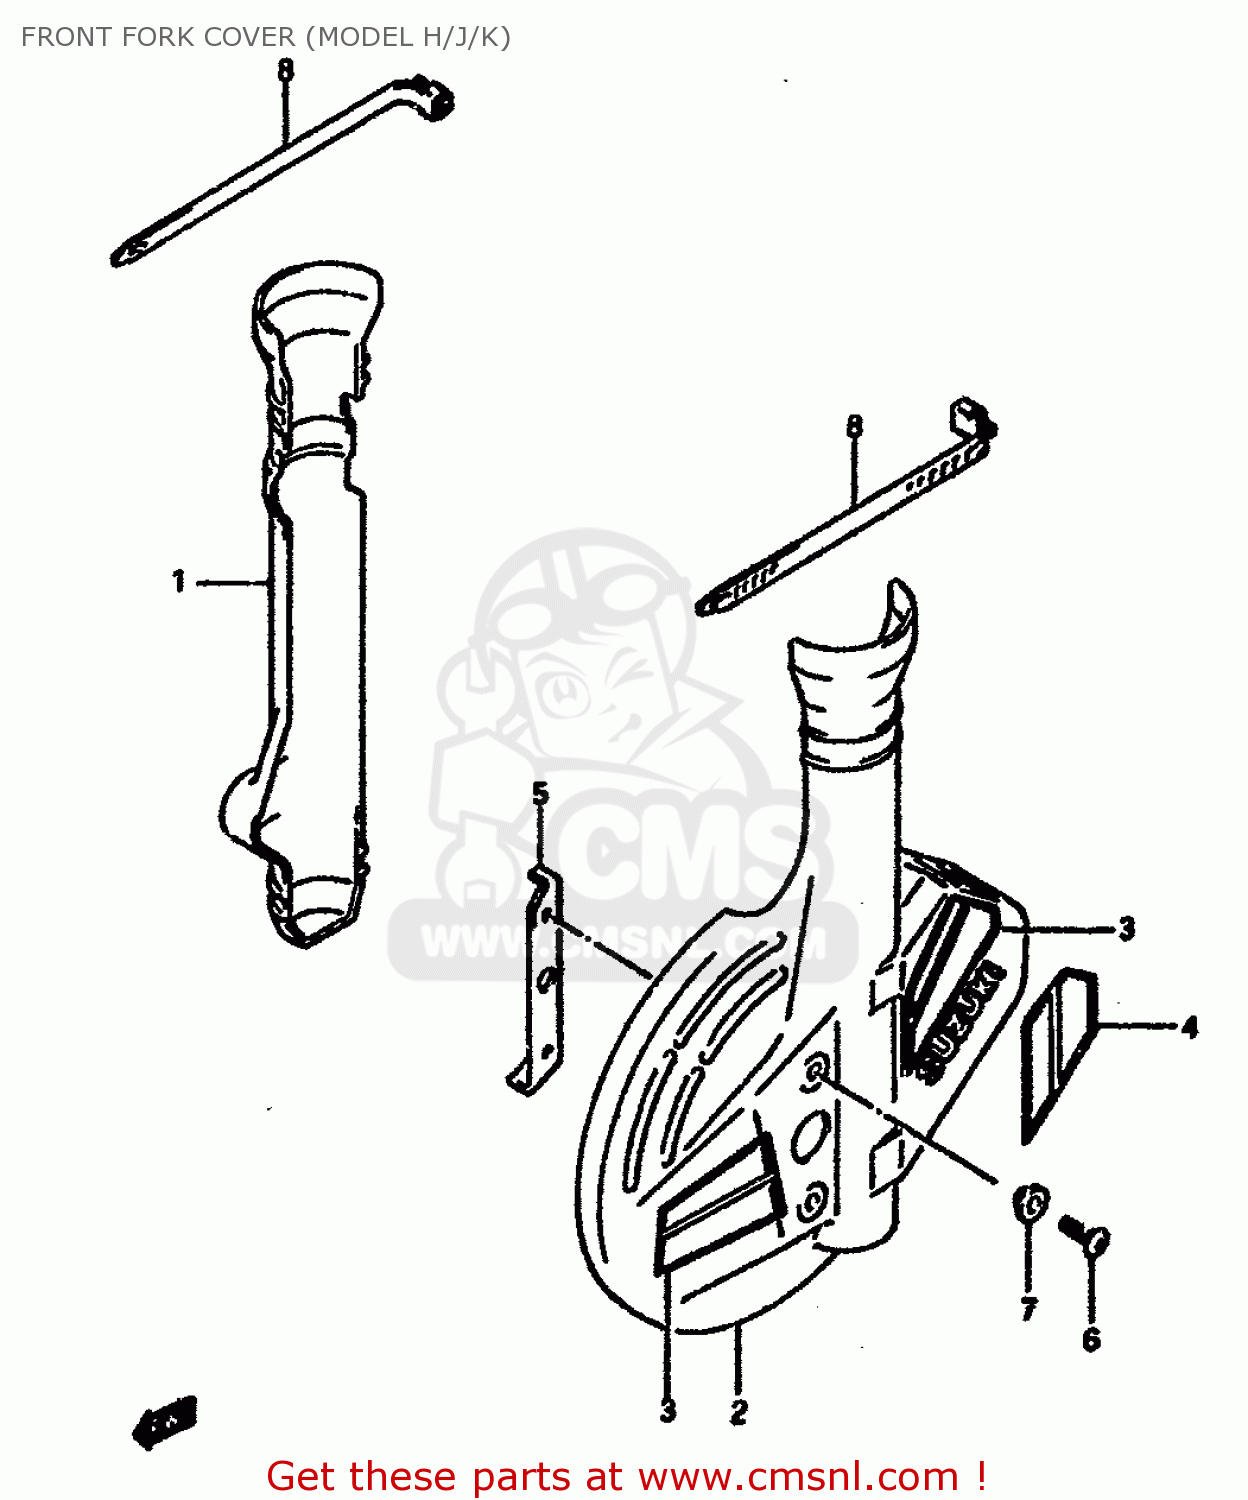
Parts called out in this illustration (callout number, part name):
1	PROTECTOR, FRONT FORK RH
2	PROTECTOR, FRONT FORK LH
3	TAPE SET,DISC PROTECTOR
4	TAPE SET,DISC PROTECTOR
5	PLATE, PROTECTOR SET
6	SCREW 6X12
7	WASHER
8	CLAMP
